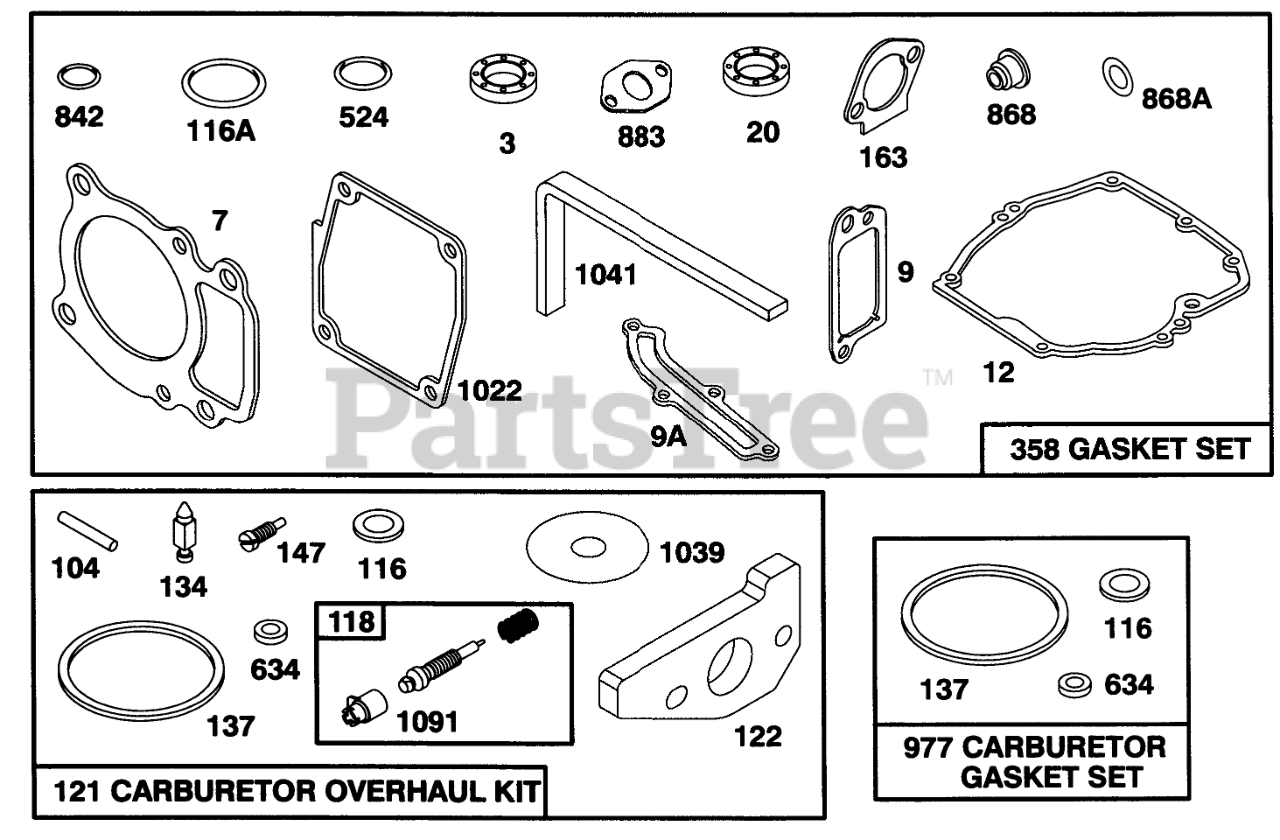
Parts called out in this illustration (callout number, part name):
3	SEAL - OIL
7	CYLINDER HEAD GASKET
9	BREATHER GASKET
9A	GASKET-BREATHER
12	ENGINE BASE GASKET
20	SEAL-OIL
104	FLOAT HINGE PIN
116	SEALING GASKET
116A	O RING SEAL
118	VALVE/SPRING - NEEDLE
121	KIT-CARBURETOR OVERHAUL
122	ADAPTER ASSEMBLY
134	Valve-Inlet (Includes Seat)
137	FLOAT BOWL GASKET
147	JET - PILOT
163	AIR CLEANER GASKET
358	GASKET SET
524	O-RING
634	SEAL WASHER
842	O-RING
868	SealAssy-Valve
868A	Seal-Valve
883	EXHAUST GASKET
977	CARBURATOR GASKET SET
1022	ROCKER COVER GASKET
1039	FLOAT LIMITER
1041	SEAL - FOAM
1091	CAP - LIMITER
